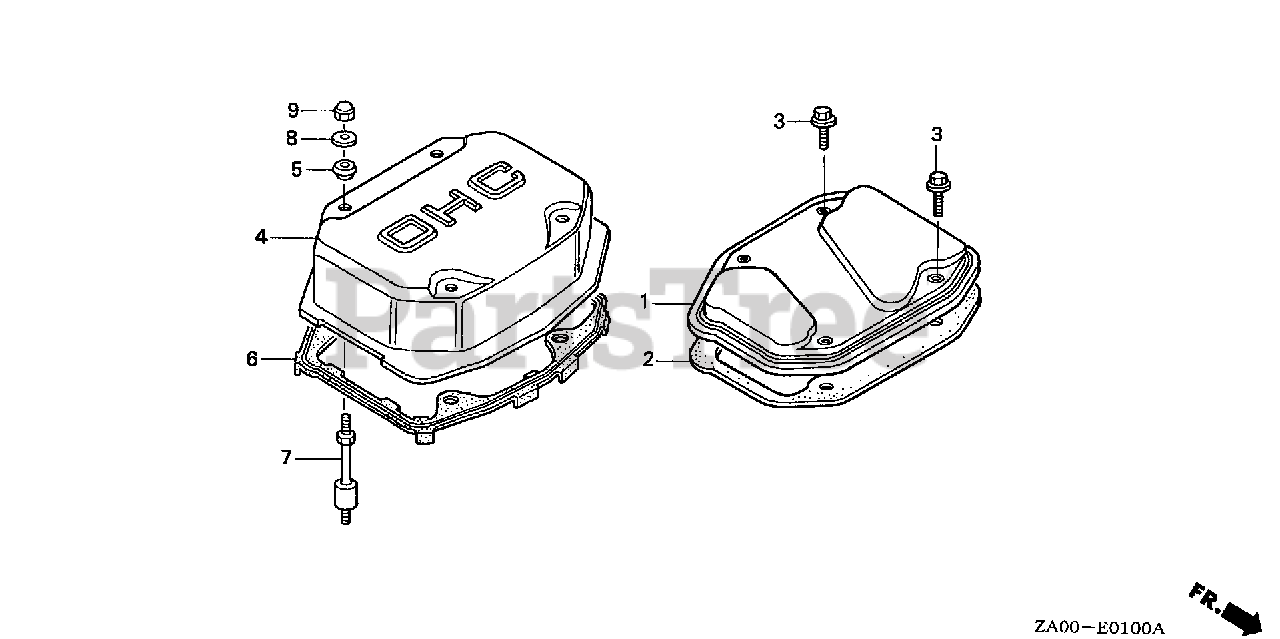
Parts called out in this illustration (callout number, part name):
1	COVER, CYLINDER HEAD
2	GASKET, HEAD COVER
3	BOLT, FLANGE (6X20)
